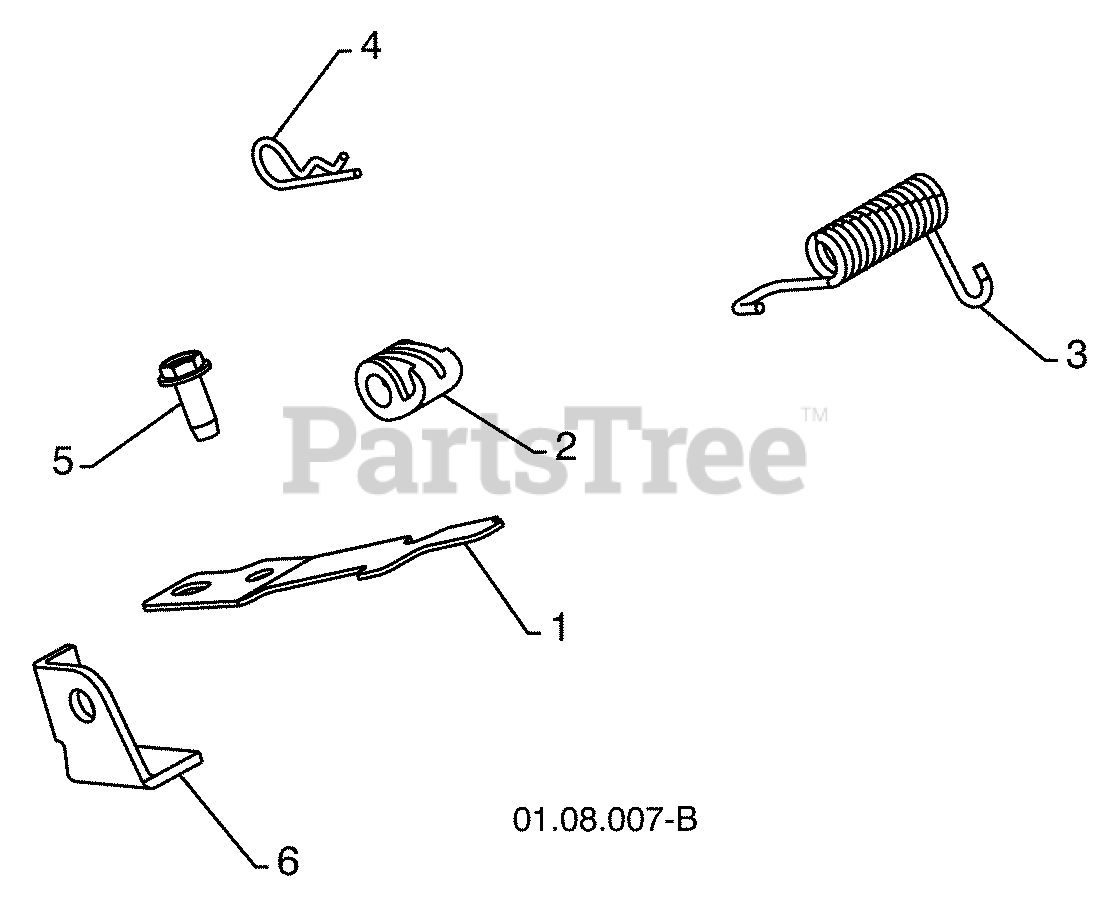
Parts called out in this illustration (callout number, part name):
1	INTERLOCK SPRING
2	INTERLOCK CAM
3	TORSION SPRING
5	SCREW 1/4-20 X .625
6	INTERLOCK STOP
